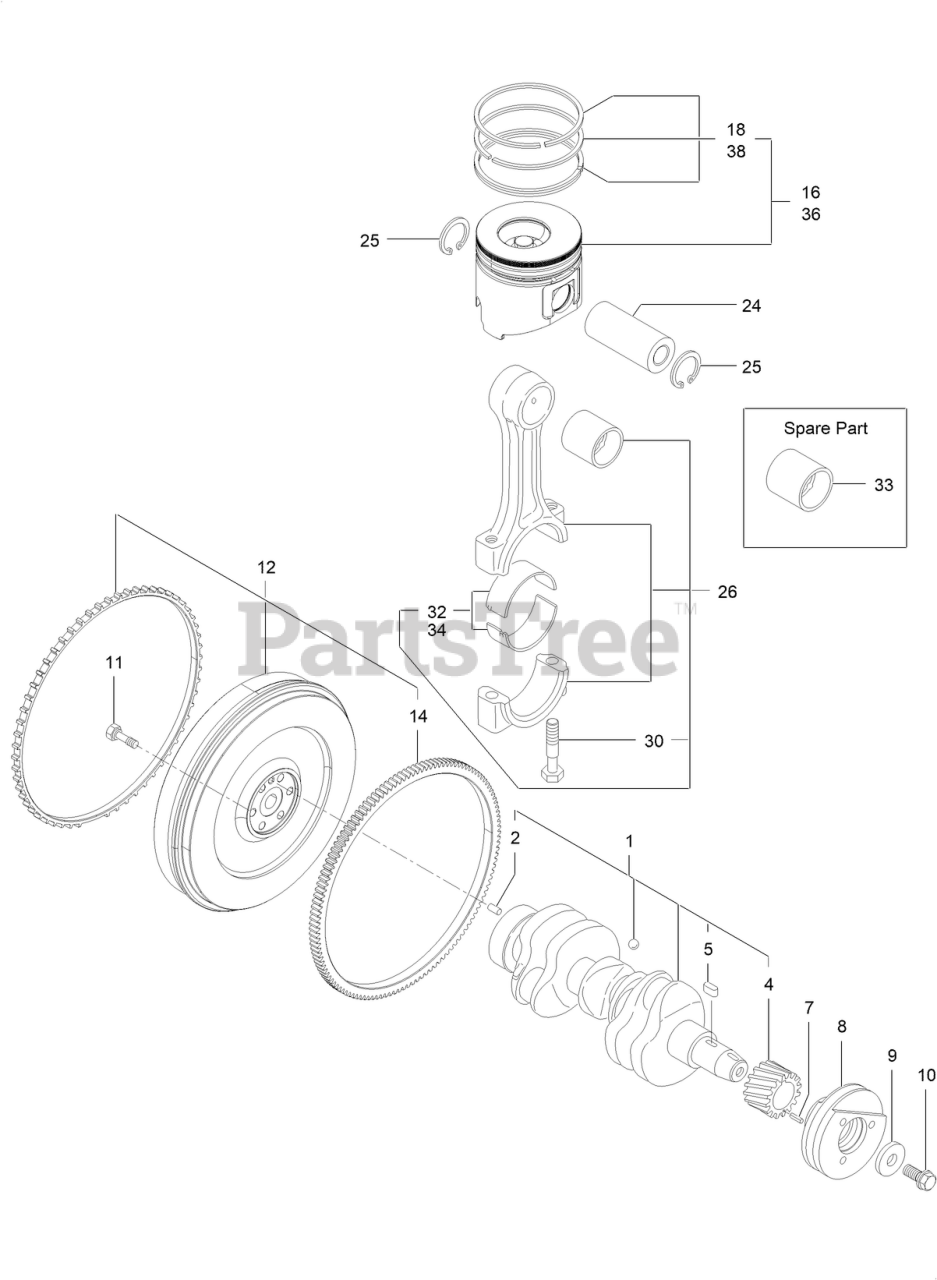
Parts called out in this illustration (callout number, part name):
1	CRANKSHAFT ASM
7	PIN-SPRING
8	PULLEY-V, CRANKSHAFT
9	WASHER
12	FLYWHEEL ASM
16	PISTON ASM
18	PISTON RING ASM
26	CONNECTING ROD ASM
32	PIN-CRANK
33	PIN-PISTON
34	PIN-CRANK (.25)
36	PISTON ASM (0.25 O.S.)
38	PISTON RING ASM (0.25 O.S.)
